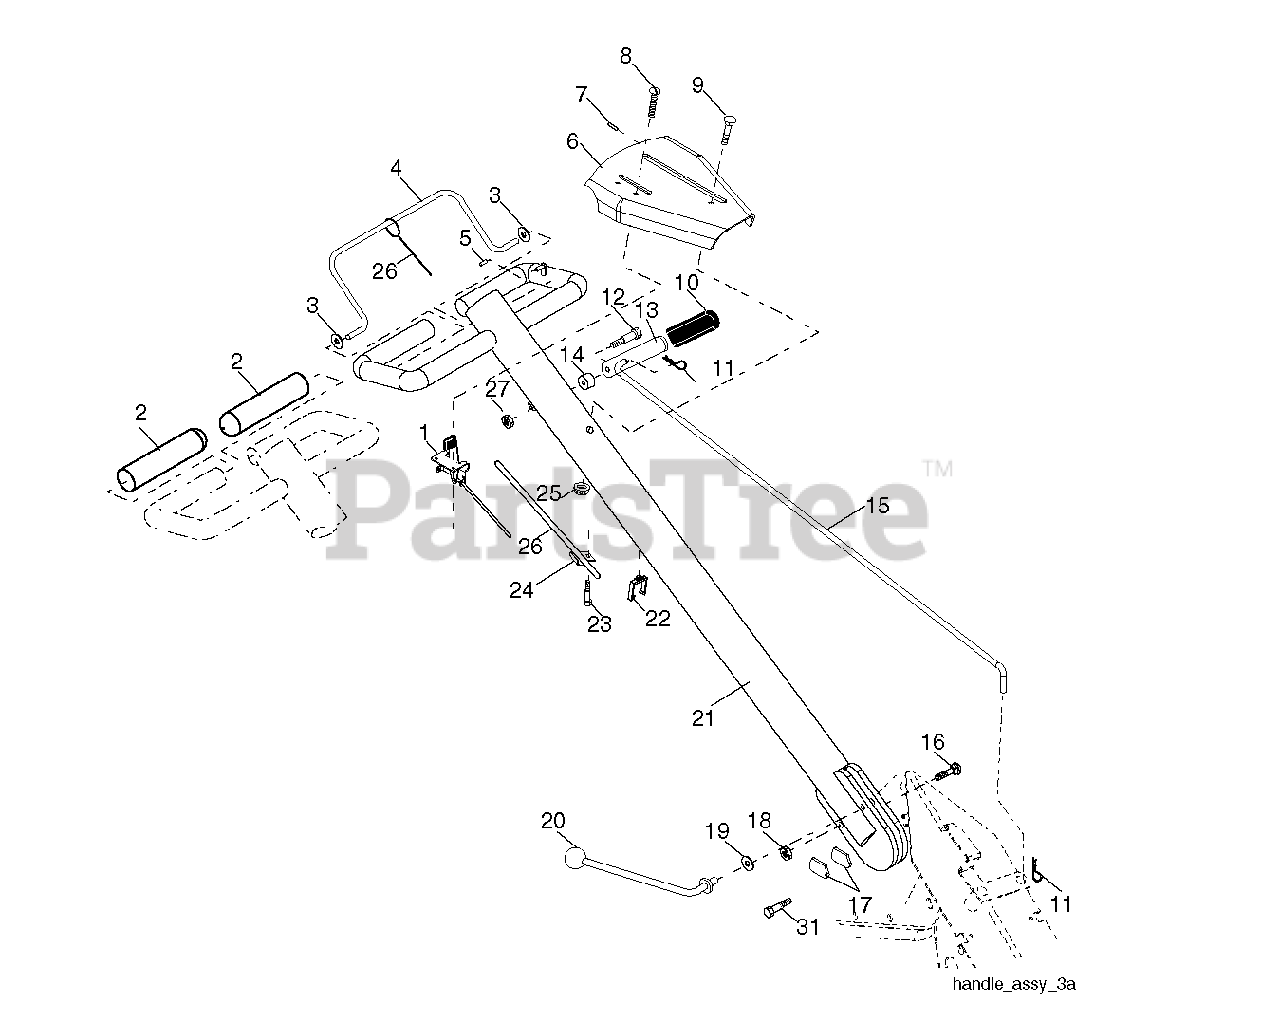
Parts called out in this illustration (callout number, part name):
1	THROTTLE.CONTROL.RT
5	VINYL CAP TI
6	PANEL, CONTROL
8	SCREW
9	BOLT.5/16-18X2.5
11	RETAINER M
12	SHOULDER BOLT ST
13	HANDLE.SHIFT.TILLER
14	GROMMET.RUBBER.CRT.TILLER
18	LOCKNUT
19	WASHER CRT
20	LEVER.LOCK.CRT
23	TAPPING SCREW
24	CONDUIT CLIP T
25	LOCKNUT-FLANGE 5/16-18
27	NUT T
31	BOLT.PIVOT
